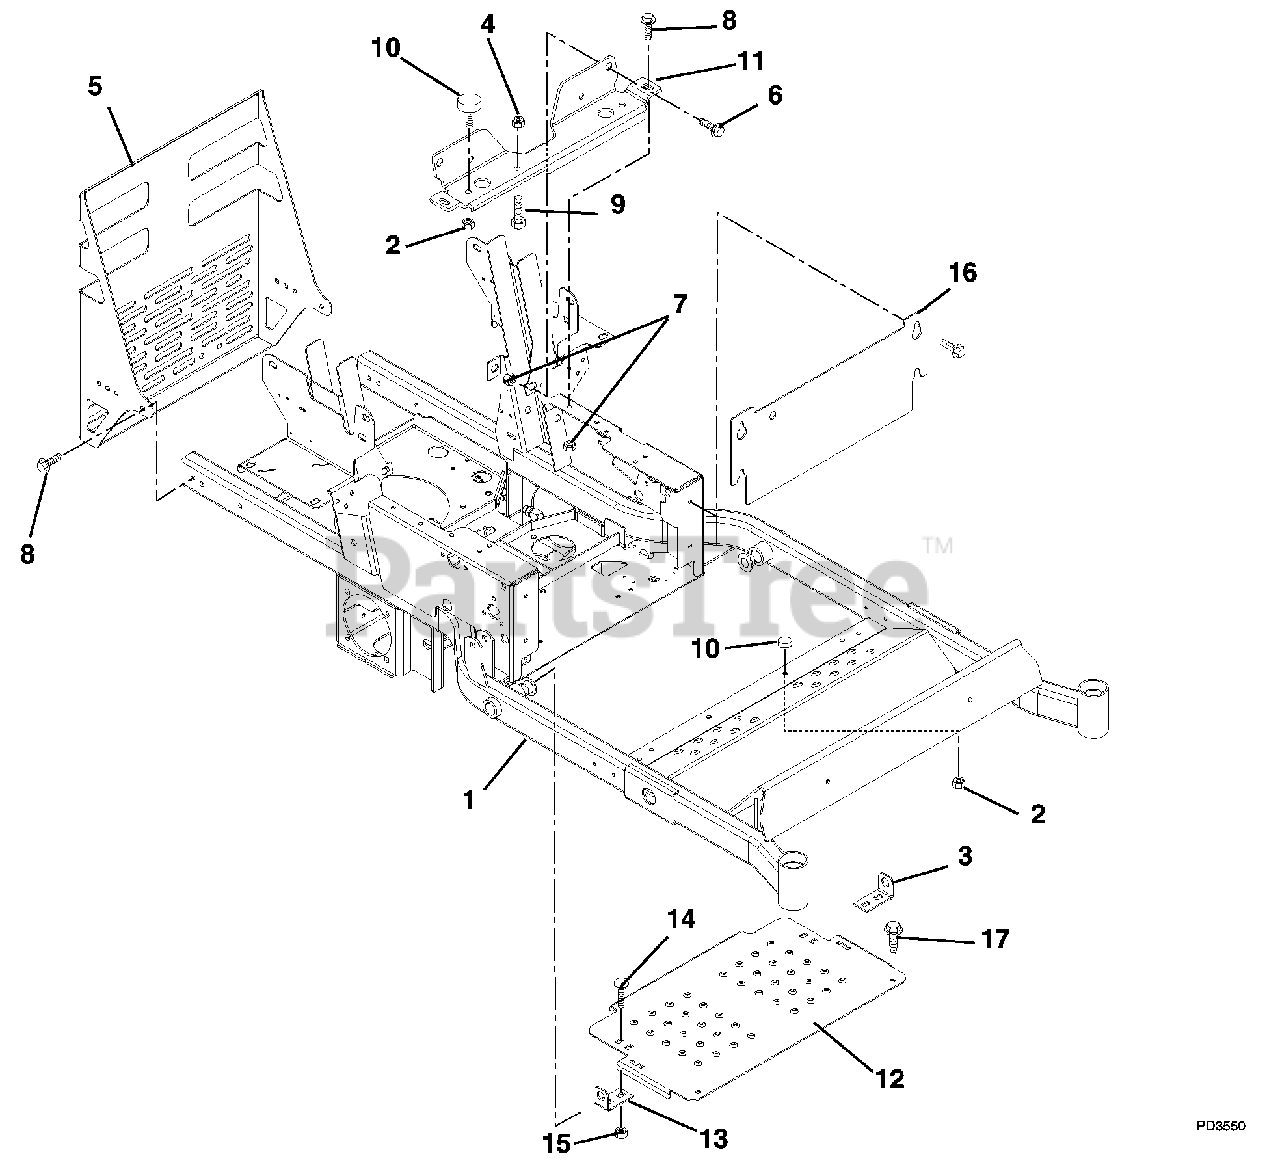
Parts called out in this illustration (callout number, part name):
1	Intermediate Z Frame (042, 043, 044, 054)
1	Intermediate Z Frame (051, 055)
2	Nut, Spin Lock Flange .312-18
3	Hinge, Footboard Left Hand
4	Nut, Locking Top Flange .31-18
5	Bumper/Guard
6	Bolt, Serrated Flange Washer Head .38-16 x 1.00
7	Nut, Retainer .375-16 x .37
8	Screw, Tapping Hex Washer Head .38-16 x .50
9	Bolt, Hex .31-18 x 1.25 Grade 5
10	Bumper, Rubber
11	Seat Support
12	Footrest Panel
13	Hinge, Footboard Right Hand
14	Bolt, Round Head Square Neck .38-16 x .75 Grade 5
15	Nut, Locking Top Flange .38-16
16	Access Panel
17	Screw, Tapping .38-16 x 1.00 Hex Washer Head (310, 311)
